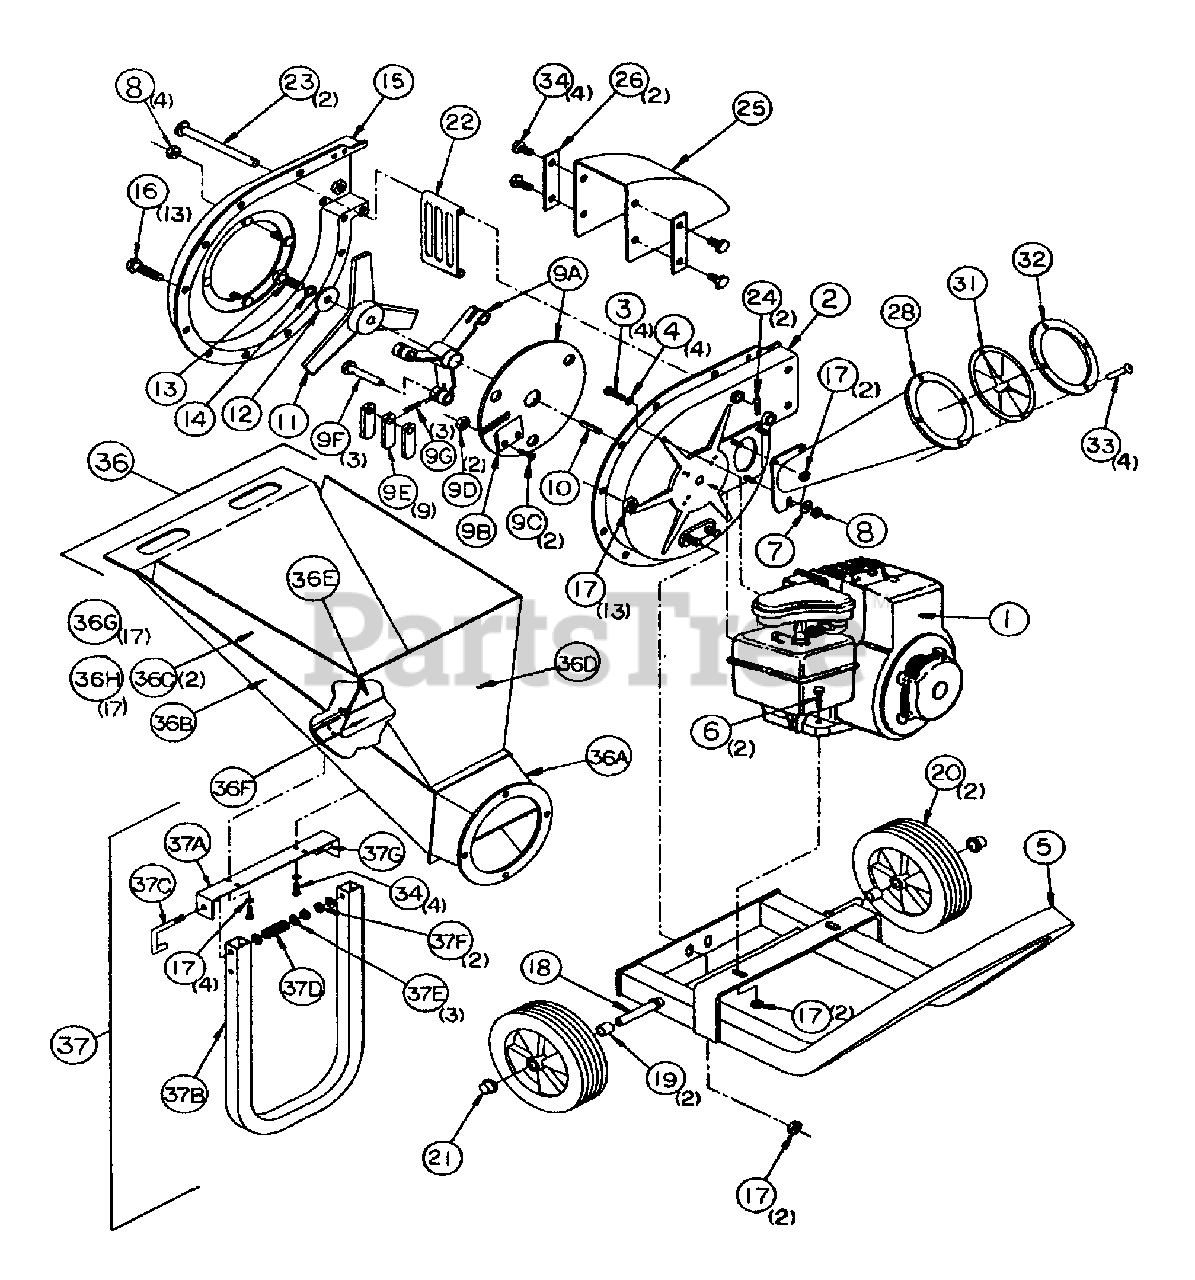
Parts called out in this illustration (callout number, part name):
1	* ENGINE, 5 HP
2	Housing Weldment, Engine Side
3	5/16-24 x 3/4" HHCS
4	5/16 Med. Split Lockwasher, Pltd.
5	Bumper Weldment
6	5/16-18 x 1-1/2" HHCS
7	5/16 Flatwasher, Pltd.
8	5/16-18 Nylon Insert Locknut, Pltd.
9A	Shredder Flywheel
9B	Chipper Knife
9C	5/16-18 x 1" Flat Hd. Socket Cap Screw
9D	5/16-18 Nylon Insert Locknut Pltd.
9F	Hammer Rod
9G	1/8" Dia. x 1" Lg. Roll Pin
10	1/4 x 1/4" x 2" Lg. Shaft Key
11	Tri-Lobed Blade
12	Retaining Washer
13	3/8-24 x 2" Lg. HHCS, GR8, Blk.
14	3/8 Med. split Lockwasher, Pltd.
15	Housing Weldment, Hopper Side
16	5/16-18 x 5/8" HHCS, GR5
17	5/16-18 Whiz Lock Nut, Pltd.
19	Axle Spacer
20	Wheels 10" Dia. x 1-3/4" Wide
21	Push Nut Cap 5/8" Dia. Shaft
22	Shredder Screen
23	Screen Rod
24	Hair Cotter Pin
25	Discharge Cover
28	Chipper Chute Weldment
31	Chipper Chute Cover
32	Mounting Range
33	3/16" x .402 Alum Pop Rivet
34	5/16-18 x 3/4" HHCS
36	Hopper Assembly
36A	Hopper Nose Weldment
36B	Hopper Base
36C	Hopper Sides
36D	Hopper Front
36E	Hopper Baffle
36F	Hopper Blowback Shield
36G	1/4-20 x 1/2" HHCS, Blk.
36H	1/4-20 Whiz Lock Nut
37	Kick Stand Assembly
37A	Bracket
37B	Leg Stand
37E	3/8" Flatwasher, Pltd.
37F	3/8"-16 Nylon Insert Locknut, Pltd.
37G	3/8-16 x 2" HHCS
